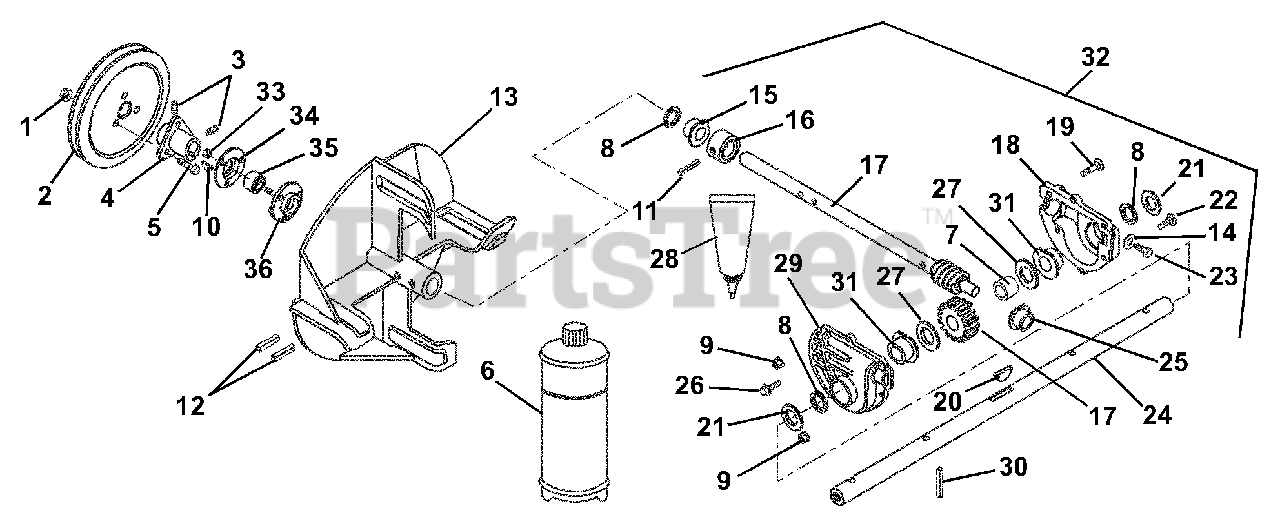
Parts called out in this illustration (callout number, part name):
1	@NUT-SPNLK-FLG .312-18 YWZC
2	PLY-V 8.50 X 1.25 3BLT
3	SCR-SET .31-18X.38 SKHCUPDL
4	HUB ASSEMBLY
5	BLT-SERRDHD SL .31-18X.75 YZ
6	ARIENS 16 OZ.BOTTLE OF L2 LUBE
7	BSHG-SLV .755X1.500X.442
8	SEAL-OIL .750X1.375X.250
9	@NUT-SPNLK-FLG .25-20 YWZC
10	KEY-WDRF .188X.875X.375 SAE11
11	PIN-GRV .188X1.25 TP A
12	PIN-ROLL .250X1.25
13	IMPELLER - 10"
14	WSHR-FIBER .437X.656X.032
15	BSHG-FLG .750X1.000X.750X1.250
16	THRUST COLLAR
17	SHAFT AND WORM GEAR ASSEMBLY
18	CASE, GEAR-LH-LARGE BORE-ALUM.
19	@BLT-RDHDSQNK .25-20X1.25 G5YZ
20	KEY-WDRF .188X.625X.25 SAE 61
21	@WSHR-FL-STL.812X1.50X.135YWZC
22	@BLT-RDHDSQNK .25-20X1.00 G5YZ
23	@SCR-TAP .38-16X.50 HWH TR YWZ
24	SHAFT, RAKE - 24"
25	BSHG-FLG .502X1X.750
26	SCR-TAP 10-24X.75 HWH TR YWZC
27	WSHR-HDND-THRST .755X1.40X.062
28	LOCTITE 518 GASKET--6ML TUBE
29	CASE, GEAR-RH-LARGE BORE-ALUM.
30	PIN-GRV .313X1.44 TP C
31	BSHG-FLG .753X1.127X.500X1.501
32	GEAR CASE - 24" - ALUMINUM
33	@NUT-LK-CTR .25-20 YWZC
34	BEARING FLANGE
35	BRG-BALL .750X1.750X.50
36	BEARING FLANGE
